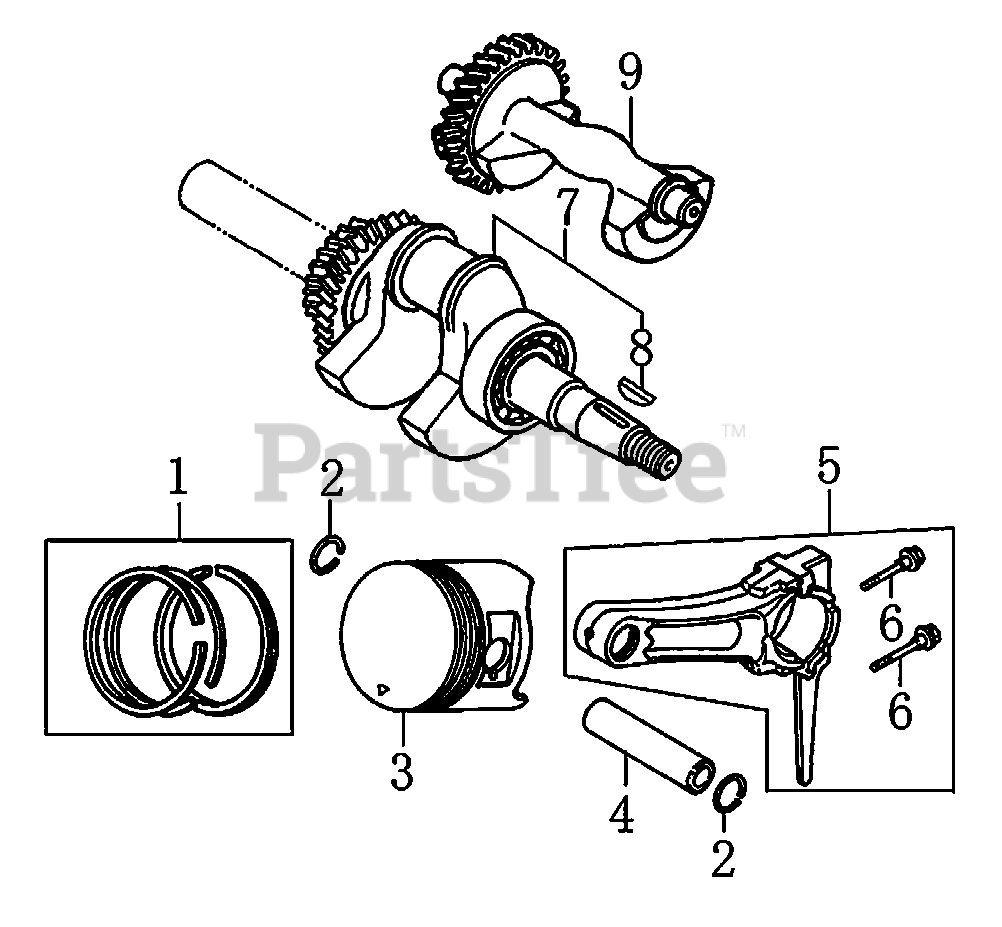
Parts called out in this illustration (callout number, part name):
1	RING SET, PISTON
2	CIRCLIP, PISTON PIN
4	PIN, PISTON
5	ROD ASSY., CONNECTING
6	BOLT, CONNECTING ROD
7	CRANKSHAFT ASSY
8	KEY, SPECIAL WOODRUFF
9	WEIGHT, BALANCER
